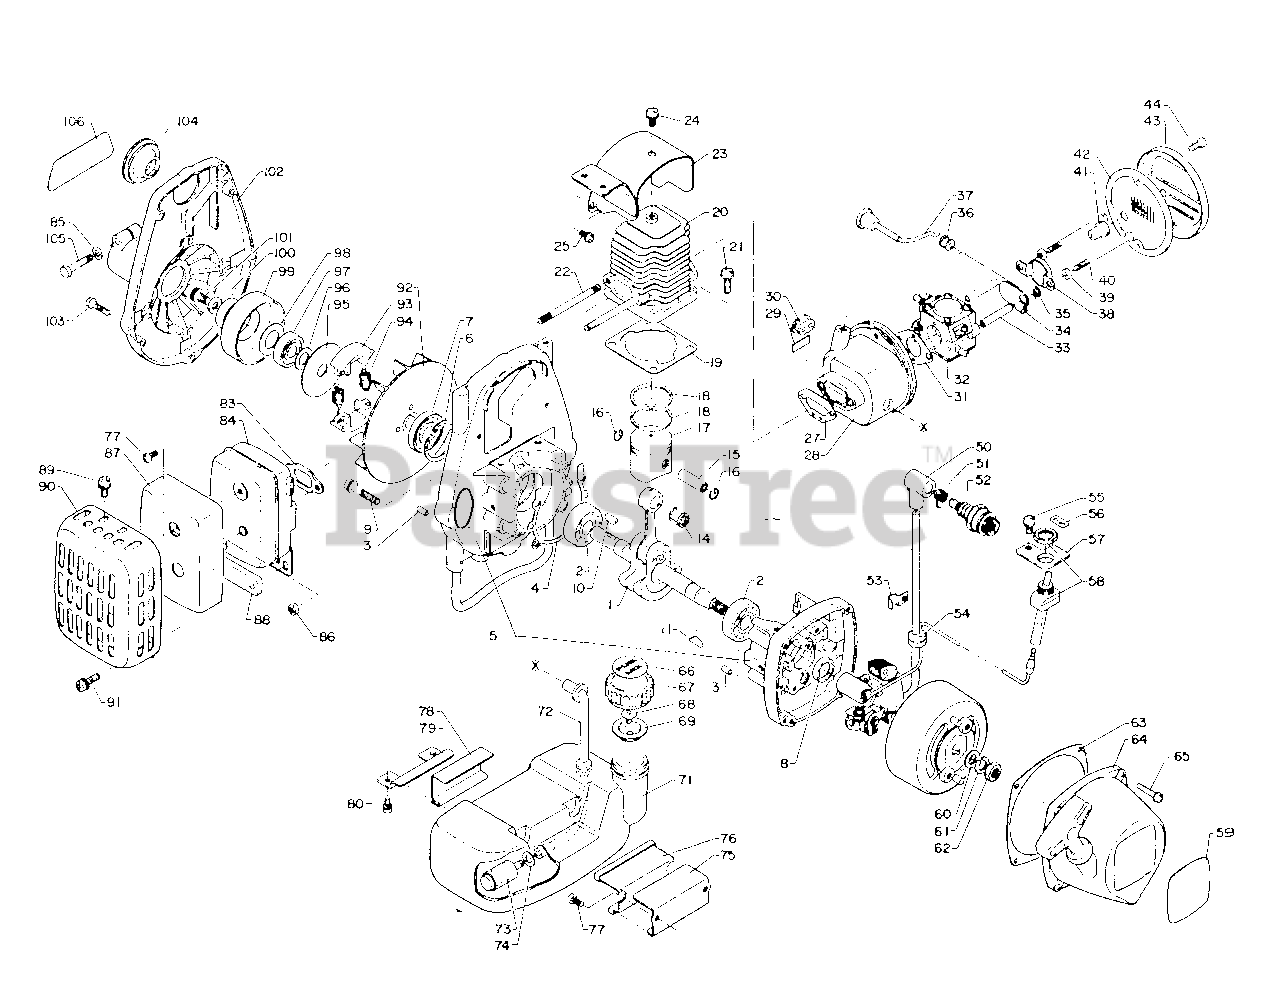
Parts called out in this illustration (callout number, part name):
1	CRANKSHAFT ASSY
2	BEARING, BALL - 6201
3	PIN - LOCATING
4	GASKET, CRANKCASE
5	CRANKCASE KIT
6	RING, RETAINING - 32
7	SEAL, OIL
8	SEAL, OIL
9	SCREW - 5X28
14	BEARING, NEEDLE
15	PIN, PISTON
16	RING, RETAINING
17	PISTON
18	RING, PISTON
19	GASKET, CYLINDER
20	CYLINDER
21	SCREW - 5X16
23	SHIELD, CYLINDER
24	SCREW - 5X10
25	SCREW - 4X8
27	GASKET, INTAKE
28	CASE, CARBURETOR
29	LABEL - CAUTION
31	GASKET, INTAKE
32	CARBURETOR WA-21
33	SPACER
34	SHUTTER, CHOKE
35	WASHER
37	ROD, CHOKE
38	PLATE, PREVENT
41	GROMMET
42	FILTER, AIR
43	COVER, AIR FILTER
44	SCREW - 4X10
50	CAP, SPARK PLUG
51	TERMINAL, SPARK PLUG CAP
52	SPARK PLUG -- BM-6A
53	CLAMP
55	SCREW - 5X10
56	LABEL - STOP
57	BRACKET, SWITCH
58	IGNITION SWITCH ASSY
59	LABEL - ECHO
61	LOCKWASHER - 8
63	GASKET, STARTER
64	STARTER ASSY
65	SCREW - 4X20
66	LABEL - FUEL MIX
67	CAP
69	HOLDER, VENT
71	TANK, FUEL
72	PIPE - FUEL
73	FILTER, FUEL
74	WASHER - 5
75	BRACKET, FUEL TANK
76	CUSHION, FUEL TANK
77	SCREW - 4X8
78	CUSHION, FUEL TANK
79	BRACKET, FUEL TANK
80	SCREW - 4X8
83	GASKET, EXHAUST
84	MUFFLER
85	WASHER - 5
86	LOCKNUT - 5
87	INSULATOR
88	SPACER
89	SCREW - 5X10
90	COVER, MUFFLER
91	SCREW - 5X16
92	FAN
93	SHOE, CLUTCH
94	SPRING, CLUTCH
95	PLATE, CLUTCH
96	WASHER, CLUTCH
97	BEARING, BALL - 6000
98	WASHER, CLUTCH
99	DRUM, CLUTCH
100	WASHER - 6
101	SCREW - 6X10
102	CASE, FAN
103	SCREW - 4X18
104	SEAL, DUST
105	BOLT - 5X25
106	LABEL - NAME
